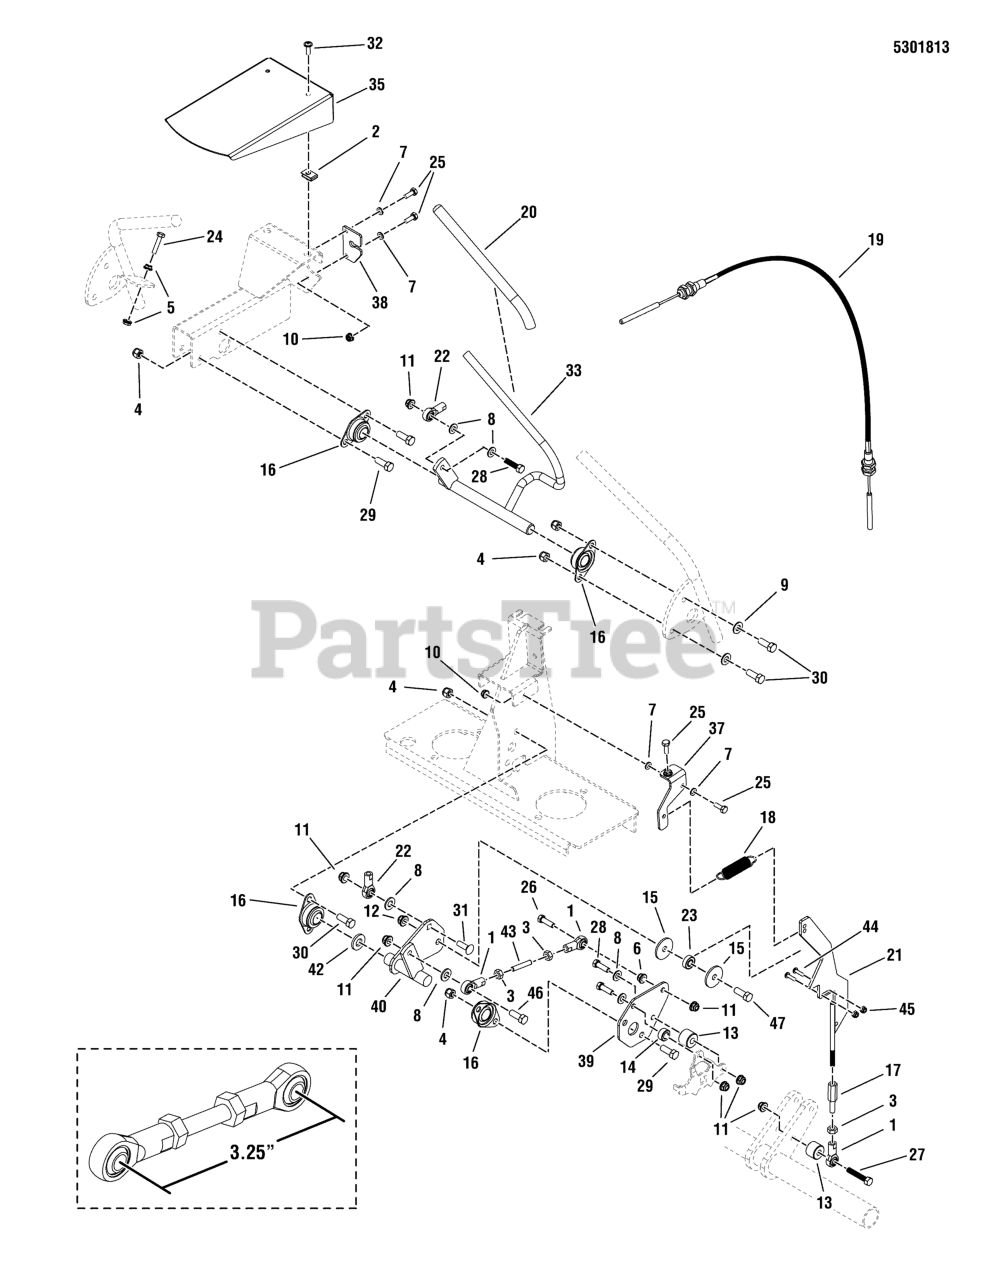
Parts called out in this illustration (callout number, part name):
1	BALL JOINT 5/16-24 RH FEMALE BRONZE RACE
2	BODY CLIP, 1/4-20 X 1/2 DEEP
3	NUT, 5/16-24 HEX
4	NUT, 3/8-16 HEX NYLON LOCK
5	NUT, 1/4-20 HEX SERR. FLANGE
6	NUT, 5/16-18 HEX SERRATED FLANGE (SMALL)
7	WASHER, 1/4 SAE
8	WASHER, 5/16" SAE
9	WASHER, 3/8 SAE
10	NUT, 1/4-20 HEX NYLOCK FLANGE
11	NUT, 5/16-18 HEX NYLOCK FLANGE
12	NUT, 3/8-16 HEX NYLOCK FLANGE
13	SPACER, .39 X 1.00 X .75
14	SPACER, .39 X .75 X .38a
15	WASHER, .390 X 1.50 X .109, YZ
16	BEARING, BRONZE FLANGE, 3/4"
17	ADJUSTER, ROD LINKAGE 5/16-24
18	SPRING-EXT, 3.281 x .751 x .075 WIRE
19	CABLE, PUSH/PULL, 30" SPEED CONTROL
20	GRIP, FOAM, .48 x 10 x .125 Black
21	WELD, CONTROL RAMP, EVO
22	ROD END, FEMALE, 10-32 W 5/16" BORE
23	BEARING, .375" ID X .875" OD X .341" THK
24	BOLT, 1/4-20 X 1-1/4, GD5
25	BOLT, 1/4-20 X 3/4 GD5 YZ
26	BOLT, 5/16-18 X 1-1/2 GD5 YZ
27	BOLT, 5/16-18 X 2, GD5
28	BOLT, 5/16-18 X 1-1/8 GD5
29	BOLT, 3/8-16 X 3/4" GD5 CZ
30	BOLT, 3/8-16 X 1" GD5 CZ
31	BOLT, 5/16-18 X 1, CARRIAGE
33	WELD,CONTROLS, HANDLE BARS, LH, EVO -RED
34	WELD,CONTROLS, HANDLE BARS, RH, EVO -RED
35	PLATE, MOTION CONTROL GUARD - RED
36	WELD, SPRING ADJUSTER, RH - RED
37	WELD, SPRING ADJUSTER, LH - RED
38	PLATE, CABLE - RED
39	PLATE, PUMP CONTROL, 48/52 - RED
40	SHAFT, LOWER CONTROL, LH - RED
41	SHAFT, LOWER CONTROL, RH - RED
42	SPACER, .76 X 1.00 X .25
43	LINK, STUD
44	SCREW, #10-24 X 3/4 ROUND PHILLIPS
45	NUT, #10-24 HEX NYLON LOCK
46	BOLT, 5/16-20 X 1-1/4, GD5
47	BOLT, 3/8-16 X 1-1/4" GD5 CZ
